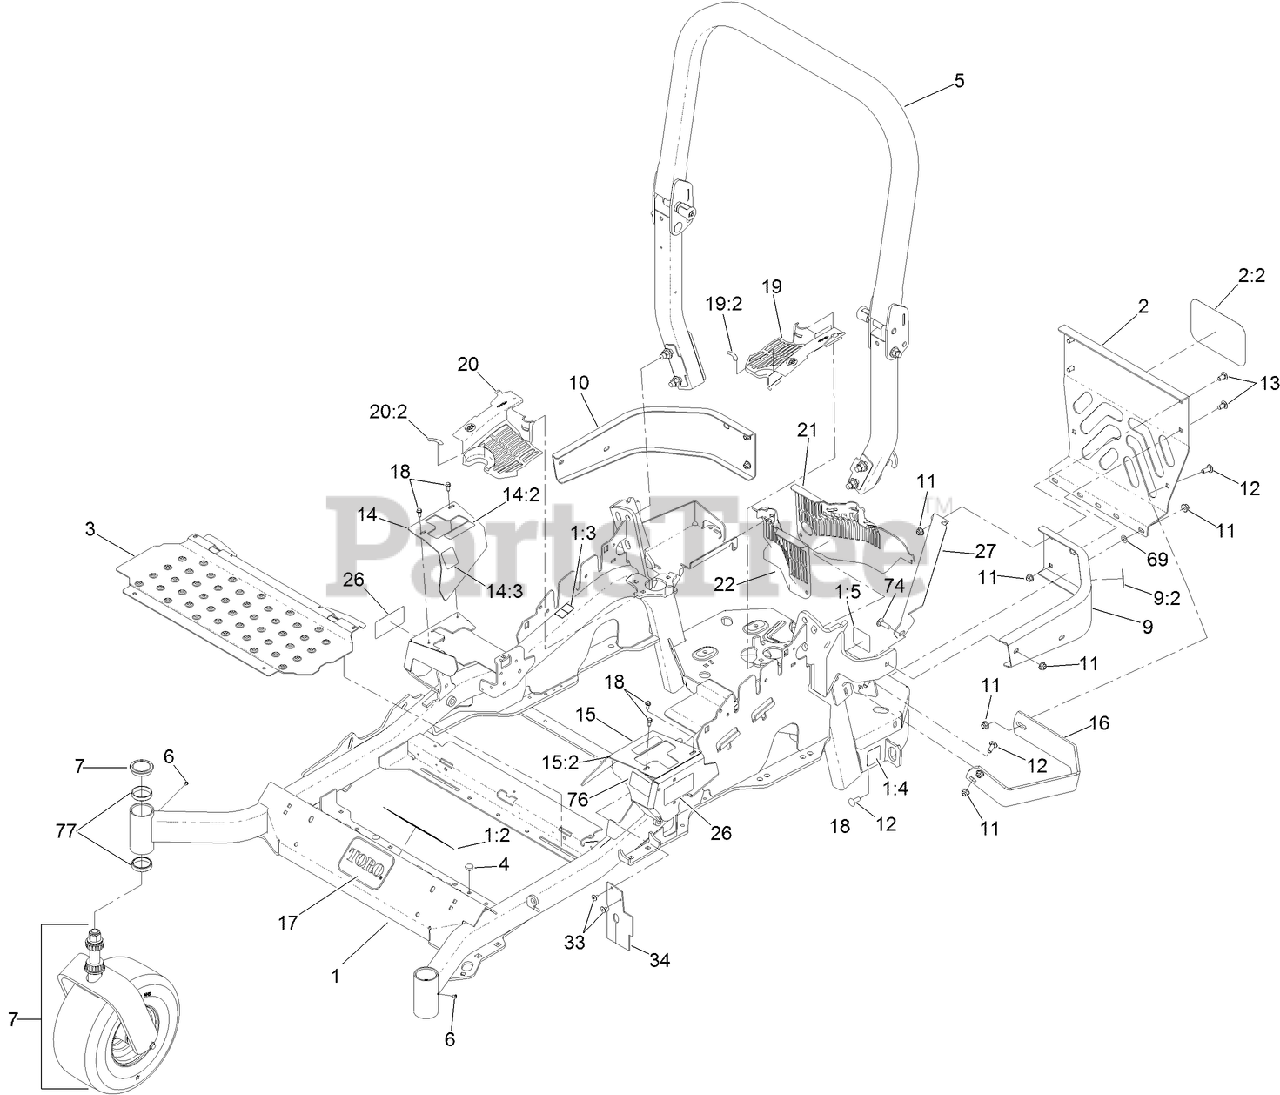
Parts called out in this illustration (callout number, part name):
1	MAINFRAME ASM
1:2	DECAL-DANGER
1:3	DECAL-WARNING
1:4	DECAL-HAZARD, PINCHED FINGER
1:5	DECAL-SPARK ARRESTER
2	REAR GUARD ASM
2:2	DECAL
3	FLOORPAN
4	BUMPER
5	ROPS ASM
7	Caster Wheel ASM
9	LH BUMPER ASM
9:2	DECAL-WARNING
10	BUMPER-RH
11	NUT-HF, NI
12	SCREW-CARR
13	SCREW-CARR
14	RH MOTION CONTROL COVER ASM
14:2	DECAL-CONTROL, MOTION
14:3	DECAL-PARK BRAKE, CE
15	LH MOTION CONTROL COVER ASM
15:2	DECAL-CONTROL, MOTION
16	GUARD-MUFFLER
17	DECAL
18	SCREW-HWH
19	LH HYDRO GUARD ASM
19:2	DECAL-OIL, HYDRO
20	RH HYDRO GUARD ASM
20:2	DECAL-OIL, HYDRO
21	GUARD-HYDRO, REAR (LH)
22	GUARD-HYDRO, REAR (RH)
33	RIVET-POP
34	DEFLECTOR-AIR FLOW
69	NUT-PUSH
74	BOLT-CARR
76	DECAL-FUEL FILL, CE
77	CUP-BEARING
